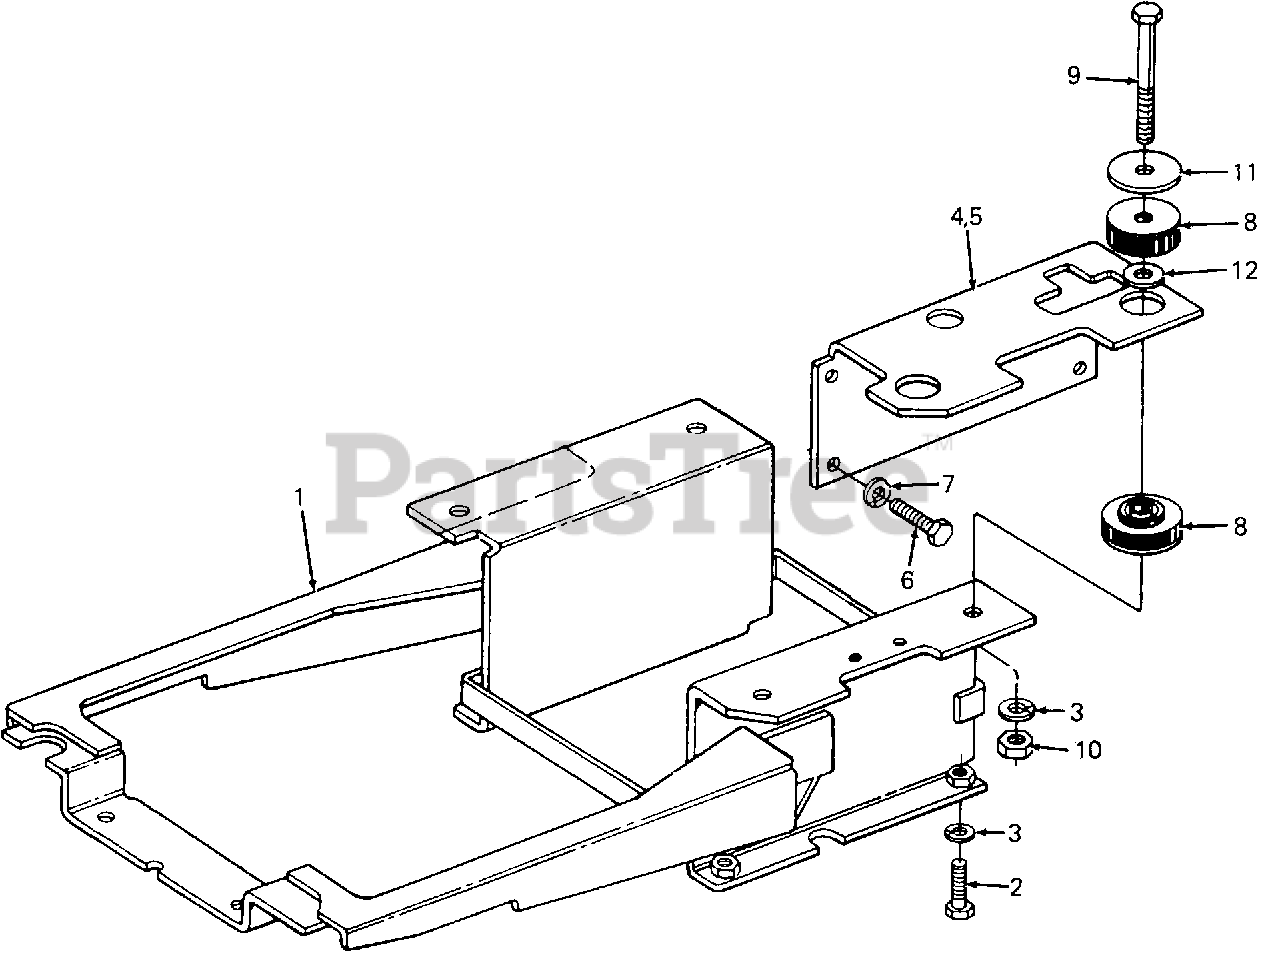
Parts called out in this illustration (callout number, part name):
1	Mount, Engine & Radiator
2	Screw, Hex Cap, 3/8-16 X 1.25 Lg GR5
3	Washer, Lock, 3/8
7	Washer, Lock, 10.2 mm
8	Isomount
9	Screw, Hex Cap, 3/8-16 X 2-1/4 Lg GR5
10	Nut, Hex, 3/8-16 GR5
11	Washer, Flat, .390 X 1.50 X .134 Thk
12	Washer, Isomount, .38 X .93 X .110 Thk HDN
